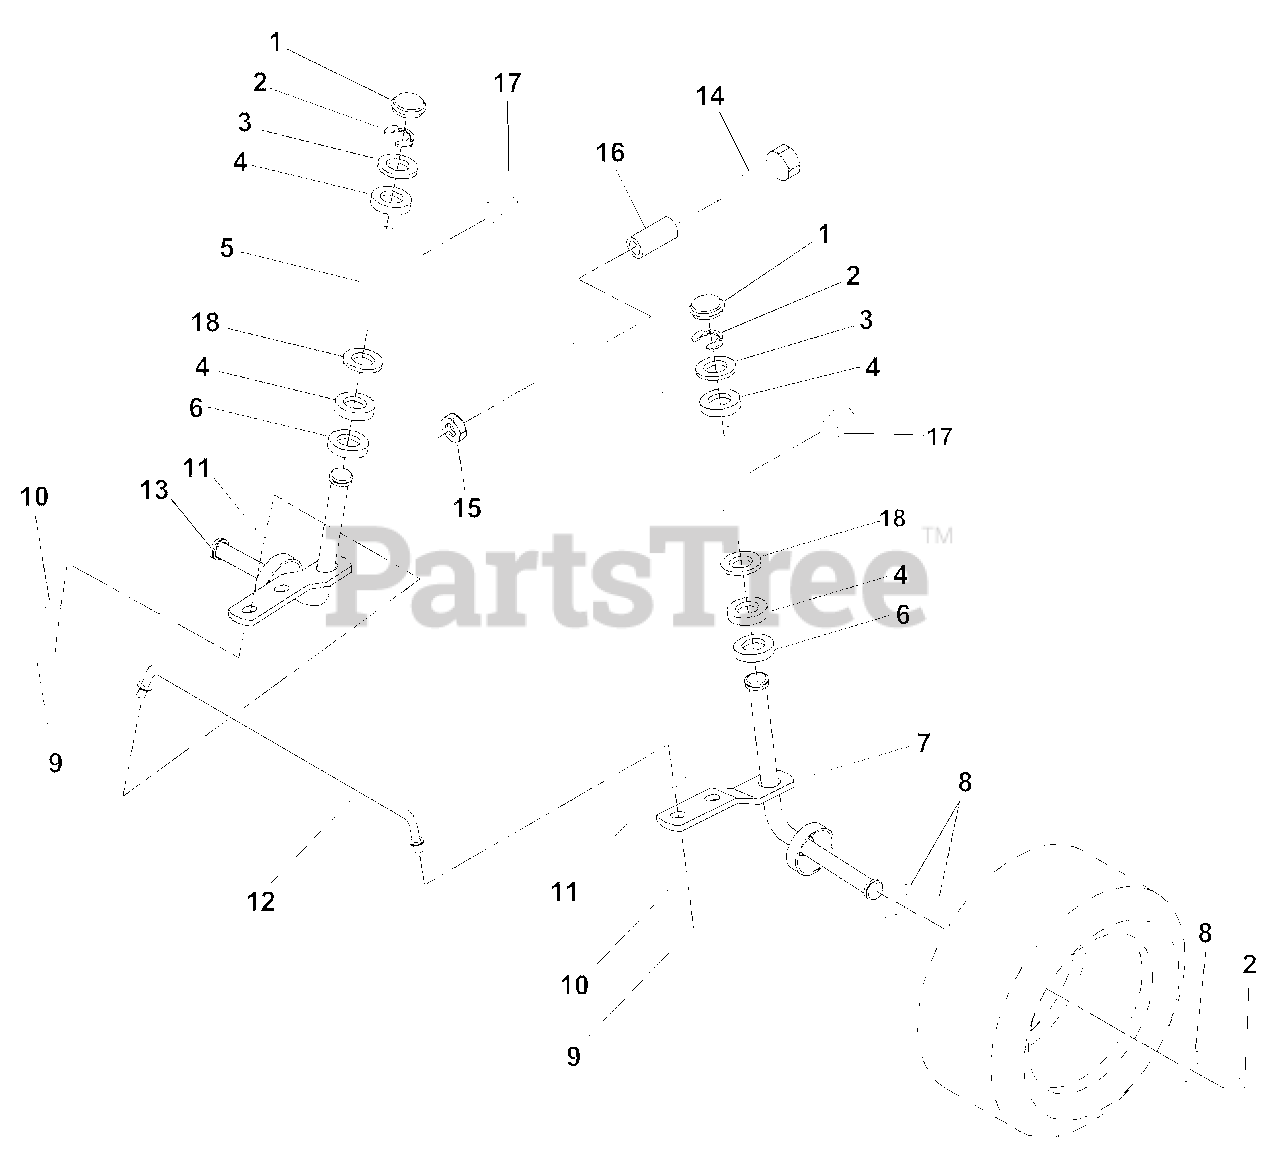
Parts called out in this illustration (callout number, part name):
1	Cap, Spindle
2	Ring, Clip
3	Washer 25/32 x 1-5/8 x 16 Gauge
4	Bearing
5	Axle, Front
6	Bearing, Thrust
7	Spindle Assembly, R.H.
8	Washer 25/32 x 1-1/4 x 16 Gauge
9	Pin, Cotter 1/8 x 3/4
10	Washer 13/32 x 13/16 x 16 Gauge
12	Tie Rod
13	Spindle Assembly, L.H.
14	Bolt Hex 5/8-11 Unc x 3-1/2
15	Nut Lock Flange 5/8-11 Unc
16	Spacer Bearing
17	Fitting Grease
18	Washer 27/32 x 1-1/4 x 16 Ga.
